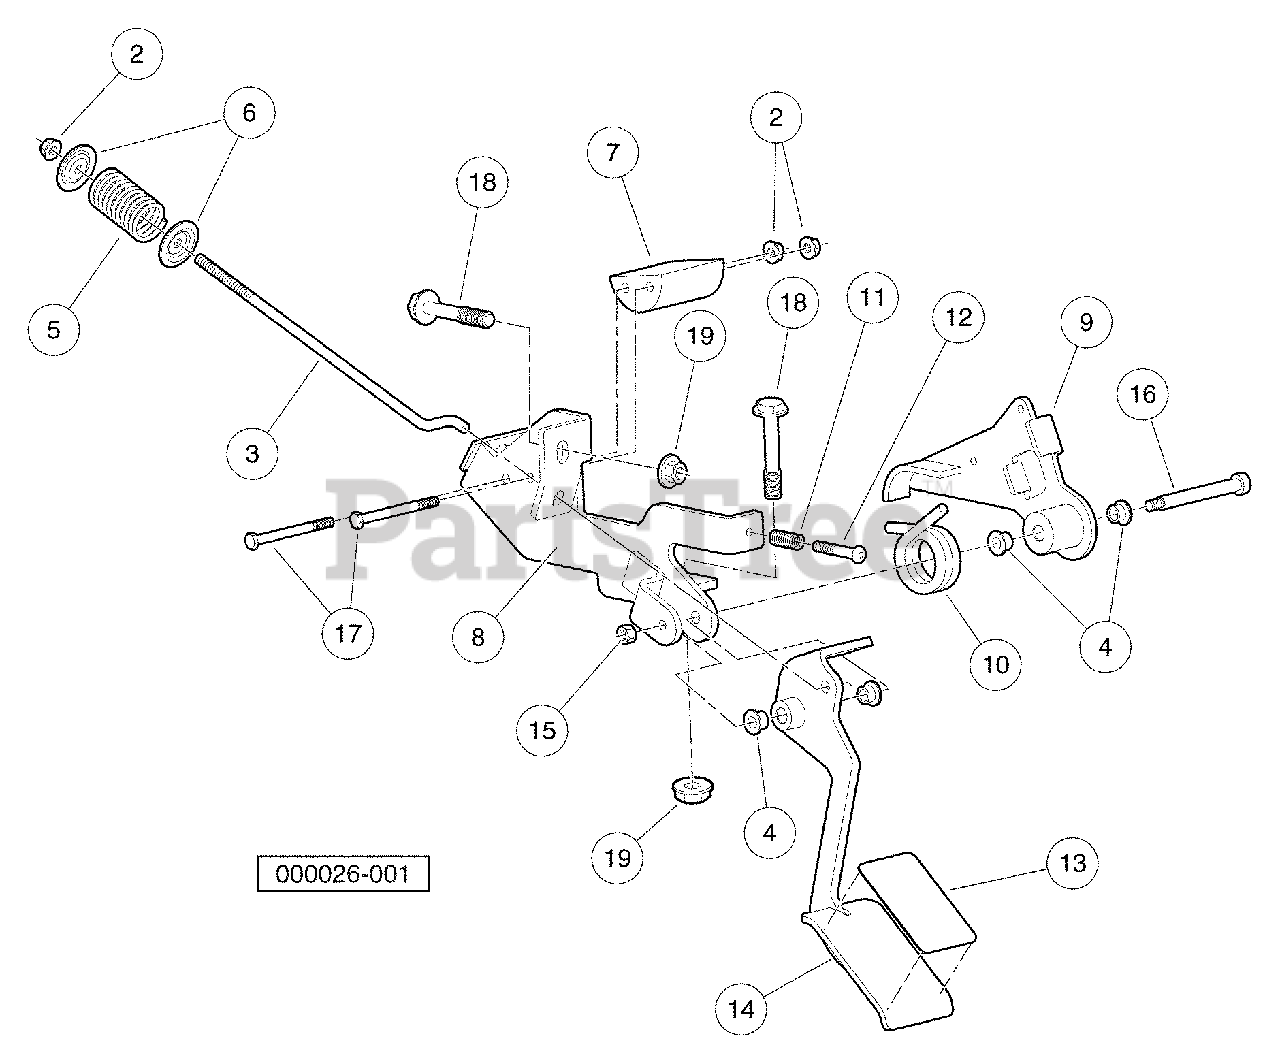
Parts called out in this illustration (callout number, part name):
1	Asm, Pedal, Accelerator
2	Nut-m6x1.0 Flng All Mtl Lock
3	Pullrod, Spring, Compression
4	Bushing, Greaseless
5	Spring, Comp, Pedal, Pullrod
7	Guide, Cable, Accelerator
8	Weldment, Bracket, Pedal
9	Weldment, Lever, Motion, Lost
10	Spring, Torsion
11	Spring, Stop, Pedal
12	Bolt, Stop, Pedal
13	Pad, Grip Tape, Accelerator
14	Weldment, Pedal, Accelerator
15	Nut M6x1 Mech Def Center
16	Bolt, Shoulder, M8 X 70, Hc
17	Bolt, M6 X 1 X 70.
18	Bolt Flanged Head, M8 X 1.25 X 65
19	Lock Nut, Flg M8 X 1.25 Nylon.
